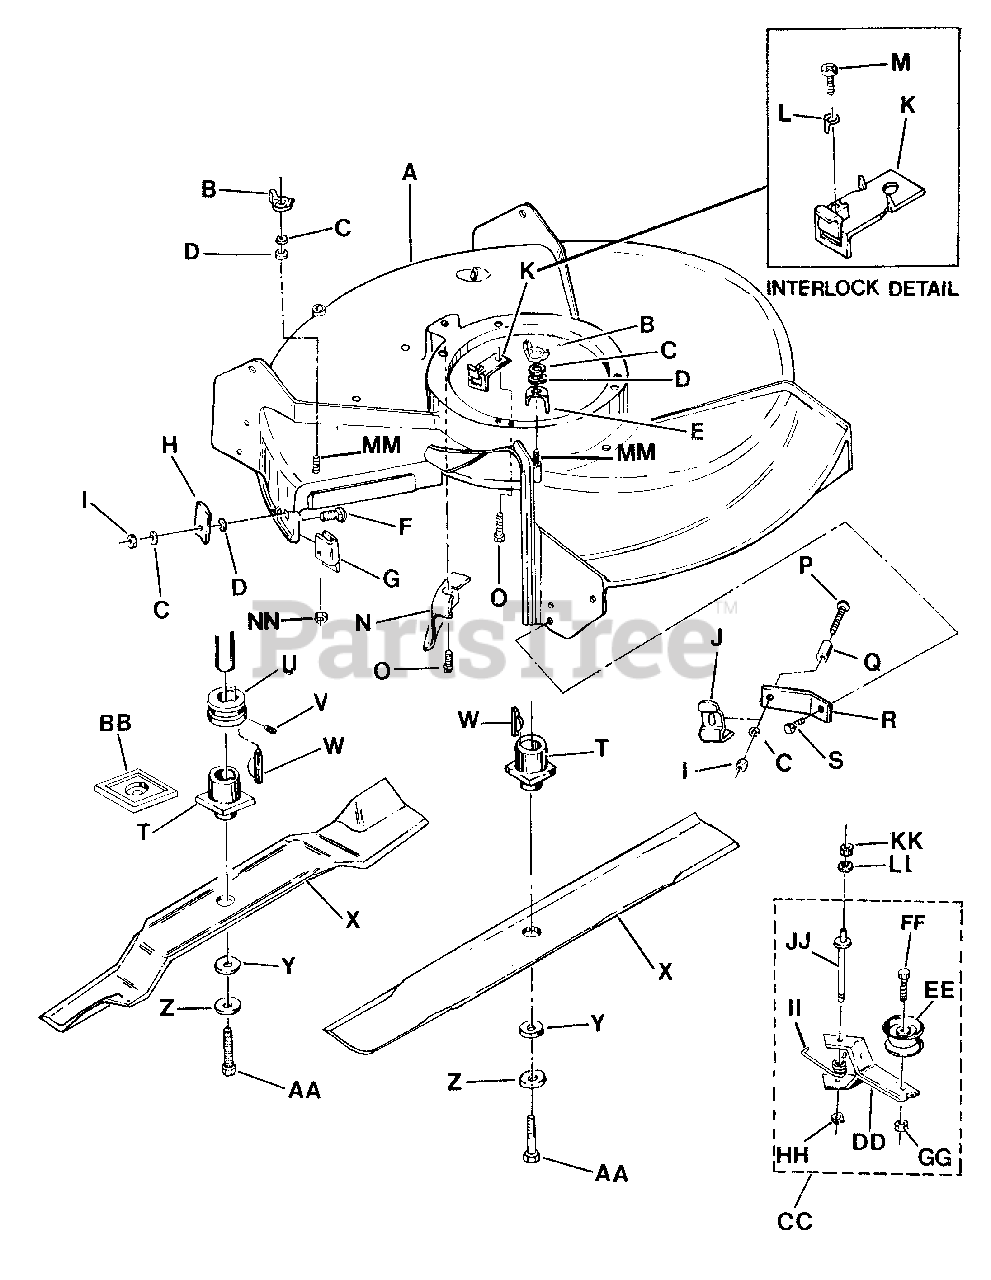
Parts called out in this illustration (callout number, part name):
A	DECK ASSEMBLY- 18" Series Cast Aluminum
B	NUT, 5/16-18 Wing
C	WASHER, 5/16 Split Lock
D	WASHER, 5/16 SAE Flat
E	CLAMP, Adapter/Side Chute
F	BOLT, 5/16-18 x 1" Square Neck Carriage, Grade 5
G	CAP, Liner
H	GUIDE, Bracket
I	NUT, 5/16-18 Hex
J	MOUNT, Bottom Plate
K	ASSEMBLY, Interlock
L	TAB-WASHER, #8
M	SCREW, #8-18 x 3/4" Sheet Metal
N	COVER, Belt Hole
O	SCREW, 3/8-16 x 1" Hex Washer Self-Tap
P	SCREW, 5/16-18 x 1-1/4" Flat Head Machine
Q	SPACER, Adapter/Chute
R	BRACKET, Side
S	SCREW, 5/16-18 x 5/8" Hex Washer Self-Tap
T	HUB, Blade Drive
U	PULLEY, Engine V21P (1-7/8" O.D., 7/8" I.D.)
V	SET SCREW, 5/16-18 x 5/16"
W	KEY, #505 Hi-Pro
X	BLADE, Cutter (18")
Y	WASHER, Cone
Z	WASHER, 3/8" Flat
AA	SCREW, 3/8-24 x 1-5/8" Hex Head Cap, Grade 5
BB	SPACER, Mulcherizer
CC	ASSEMBLY, Idler
DD	BRACKET, Idler
EE	PULLEY, Idler
FF	SCREW, 1/4-28 x 1-3/8" Hex Head Cap, Grade 5
GG	NUT, 1/4-28 Hex Top Lock
HH	RING, External Retaining
II	SPRING, Idler
JJ	STUD, Idler
KK	NUT, 3/8-24 Hex
LL	WASHER, 3/8" Internal Tooth Lock
MM	STUD, 5/16-18 x 1-1/2" Self-Tap
NN	NUT. 5/16-18 Hex Jam
